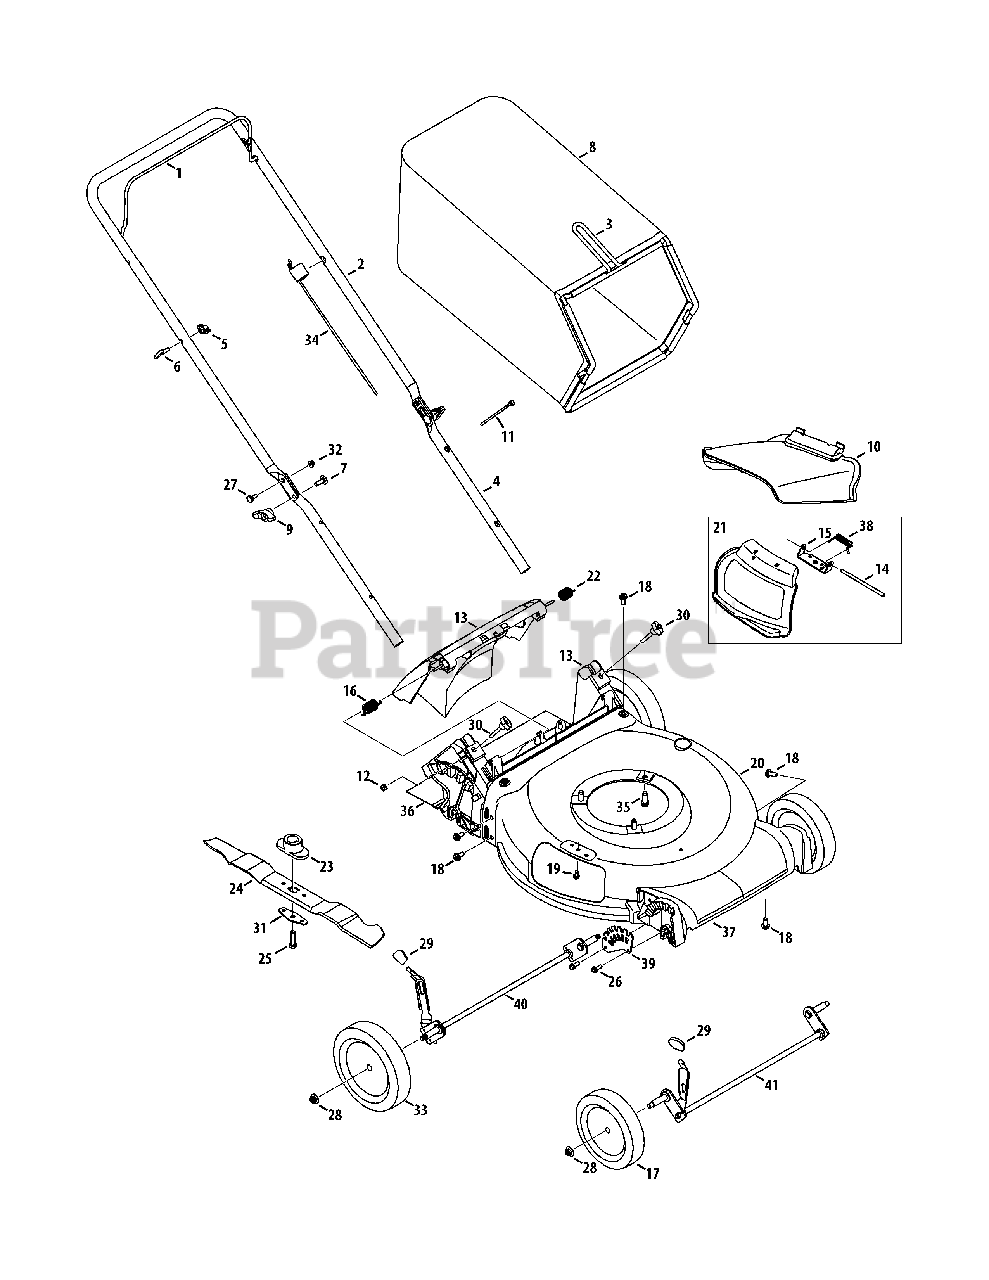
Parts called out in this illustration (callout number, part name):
1	Blade Control
2	Upper Handle
3	Grass Catcher Frame
4	Lower Handle
5	Wing Nut
6	Rope Guide
7	Carriage Screw ,5/16-18
8	Grass Bag
9	Wing Knob
10	Side Chute
11	Cable Tie
12	Nut, Sq., 1/4-20
13	Rear Discharge Door Assembly
14	Hinge Pin
15	Chute Deflector Bracket
16	Torsion Spring - RH
17	Front Wheel Gray
18	Screw, 5/16-14 x .750
19	Screw, 1/4-20 x .500
20	Deck , 21"
21	Hinged Mulch Plug Assembly
22	Torsion Spring - LH
23	Blade Adapter
24	Mulching Blade
25	Screw , 3/8-24 x 1.50
26	Screw, 1/4-15 x .750
27	Sldr. Screw, .375 x .126 x 1/4-20
28	Flange Lock Nut, 3/8-16
29	Adjustment Lever Knob
30	Wing Nut
31	Blade Bell Support
32	Nut, Flange Lock, 1/4-20
33	Rear Wheel Gray
34	Control Cable, 37.58"
35	TT Sems Screw, 3/8-16 x 1.0
36	Trail shield
37	Front Cover
38	Torsion Spring
39	Front Height Adjuster Plate
40	Rear Axle Assembly
41	Front Axle Assembly
